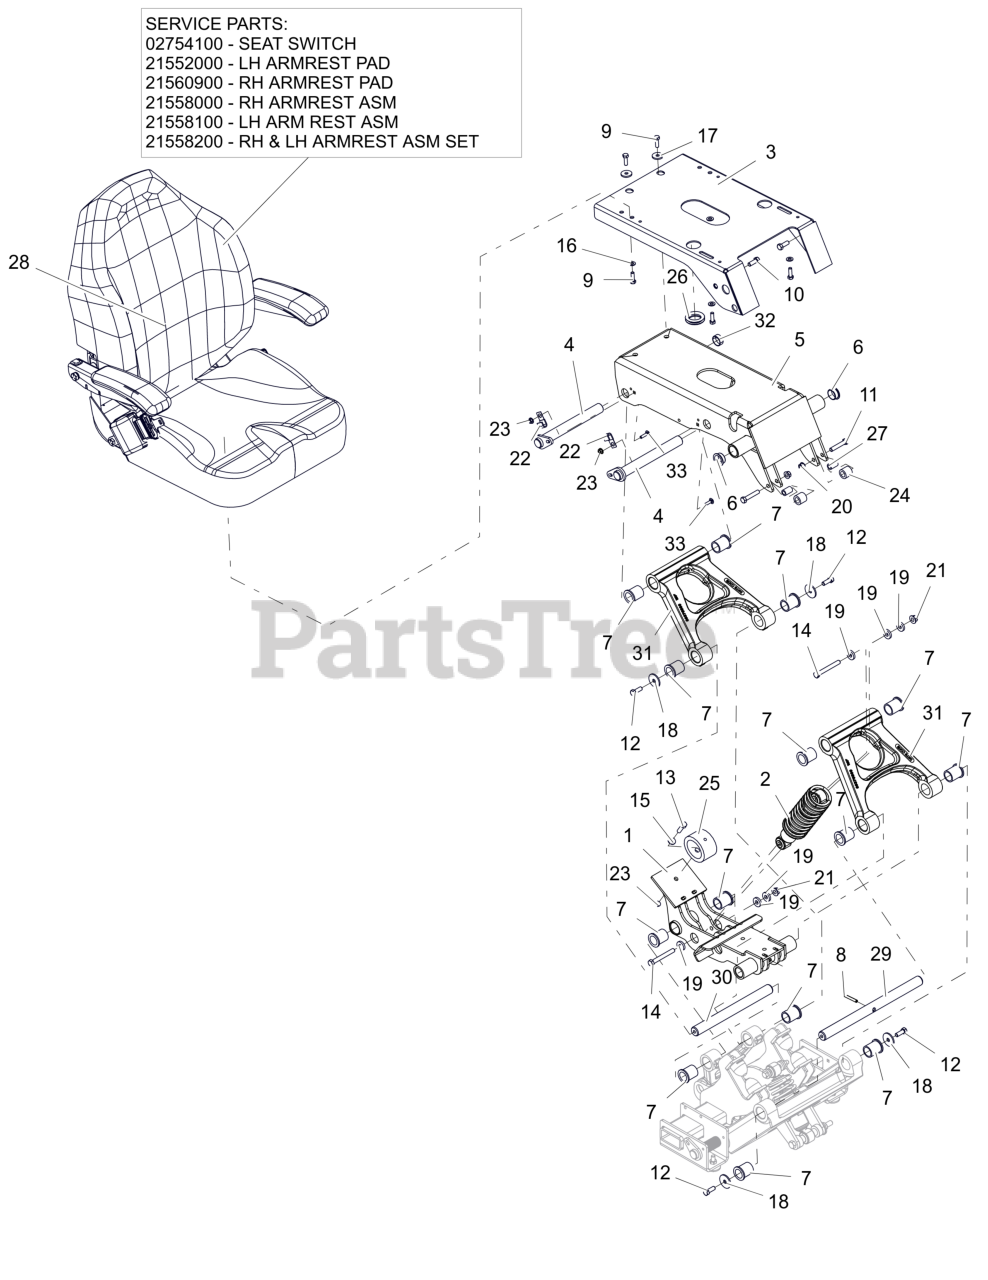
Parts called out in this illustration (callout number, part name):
1	MACHINED, SUSPENSION MID LINK (BLACK)
2	SHOCK, UPPER - TENNECO
3	WLDMT- SEAT MOUNT - RED
4	WLDMT, UPPER PIVOT SHAFT (RED)
5	WLDMT, SEAT MOUNTING SUPPORT (RED) W/ SAFETY DECALS
6	BSHG-FLG 1.0X1.125X.50X1.375 R
7	BEARING, SINTERED BRONZE FLANGE
8	PIN-ROLL .250X1.75
9	BLT,HEX .31-18X1.00 G5 ZCC
10	BLT,HEX .38-16X1.00 G5 ZCC
11	BLT,HEX .38-16X2.00 G5 ZCC
12	BLT, HEX .38-16X1.00 G8ZCCEP30
13	BLT, HEX .38-16X1.25 G5 ZCC
14	BLT,HEX M10-1.5X80 G10.9 ZCC
15	WSHR,FLT .406X.812X.065 ZCC
16	WSHR,FLT .344X.688X.065 ZCC
17	WSHR, FLT .340X1.125X.135 ZCC
18	WSHR, FLT .380X1.50X.125 ZCC
19	WSHR, FLT .406X1.00X.188 ZCC
20	NUT-LK-CTR-FLG .375-16 GF ZCC
21	NUT, FLG-CTR LK M10-1.50 ZCC
23	NUT-LK-CTR-FLG .25-20 ZC120
24	BUMPER,RUBBER .62X1.0X.88 LG
25	BUMPER, RADIAL (GBR)
26	GROMMET 1.25ID X 1.5OD
27	BUSH.,S.391X.622X.950 ST
28	SEAT, PT600
28	SWITCH- SNAP MTG N.O.
28	PAD, ARMREST LH
28	PAD, ARMREST RH OR LH (HARD)
28	ARMREST, RH ASSEMBLY
28	ARMREST, LH ASSEMBLY
28	SET, RH & LH ARMREST ASSEMBLY
29	SHAFT, PIVOT
30	SHAFT, PIVOT
31	MACHINED, UPPER LINK
32	CAP, 1.000 ID X .375 DEEP
33	BLT, RHSN .25-20X1.00 G5 ZCC
